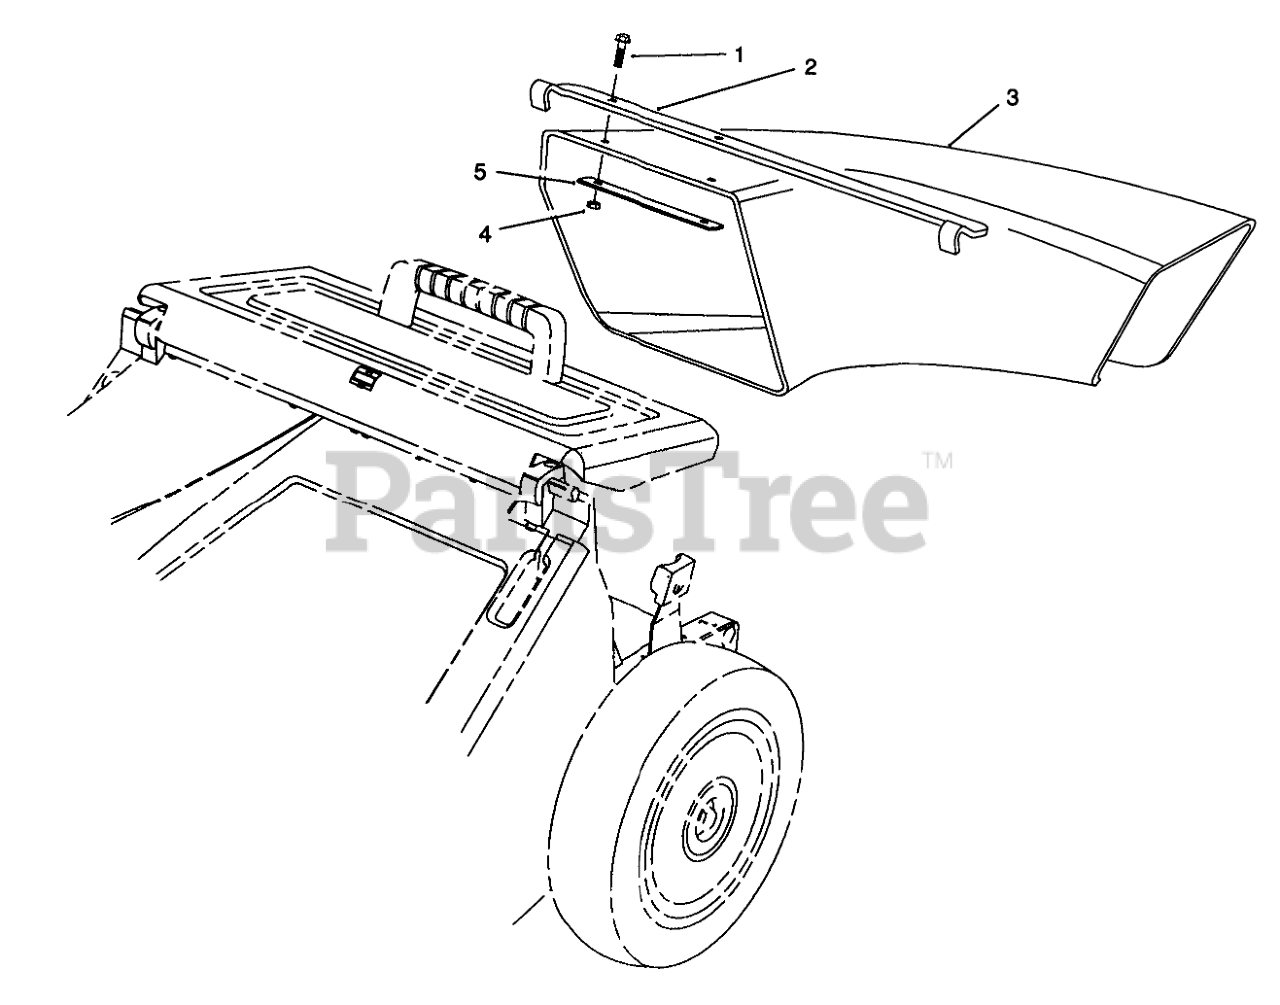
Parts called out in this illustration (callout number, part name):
1	SCREW-HWH
2	CHUTE HANGER BRACKET
3	Chute-Discharge
4	NUT-LOCK, NI
5	STRESS PLATE
